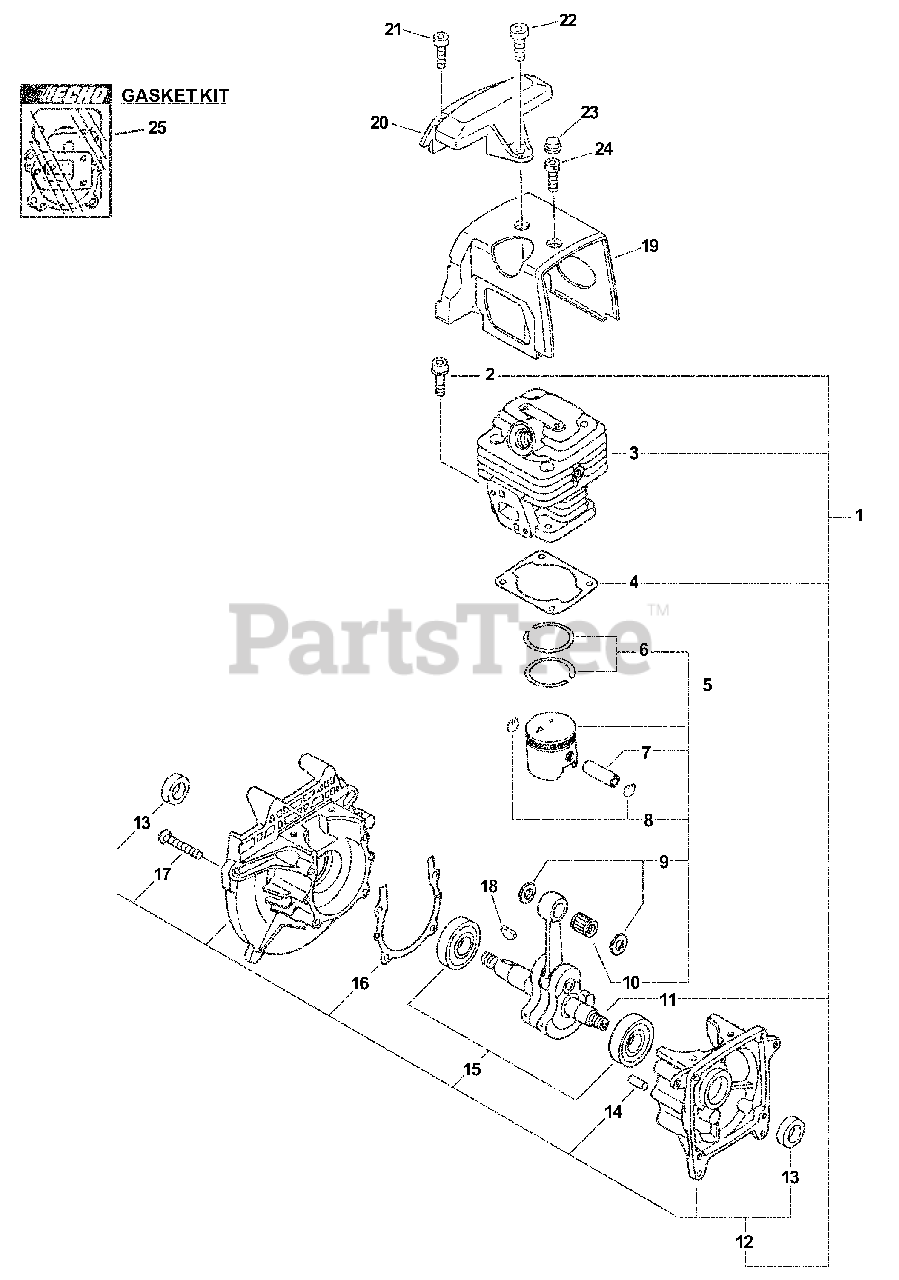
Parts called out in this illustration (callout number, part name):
1	SHORT BLOCK -- SB1029
2	SCREW - 5X20
3	CYLINDER
4	GASKET, CYLINDER
5	PISTON KIT
6	RING, PISTON
7	PIN, PISTON
8	RING, RETAINING
9	SPACER, PISTON
10	BEARING, NEEDLE
11	CRANKSHAFT ASSY
12	CRANKCASE KIT
13	SEAL, OIL
14	PIN - LOCATING
15	BEARING, BALL - 6201
16	GASKET, CRANKCASE
17	SCREW - 5X30
19	COVER, ENGINE
20	GUARD - TOP
21	SCREW - 4X14
22	SCREW - 5X16
24	SCREW - 5X12
25	GASKET KIT
